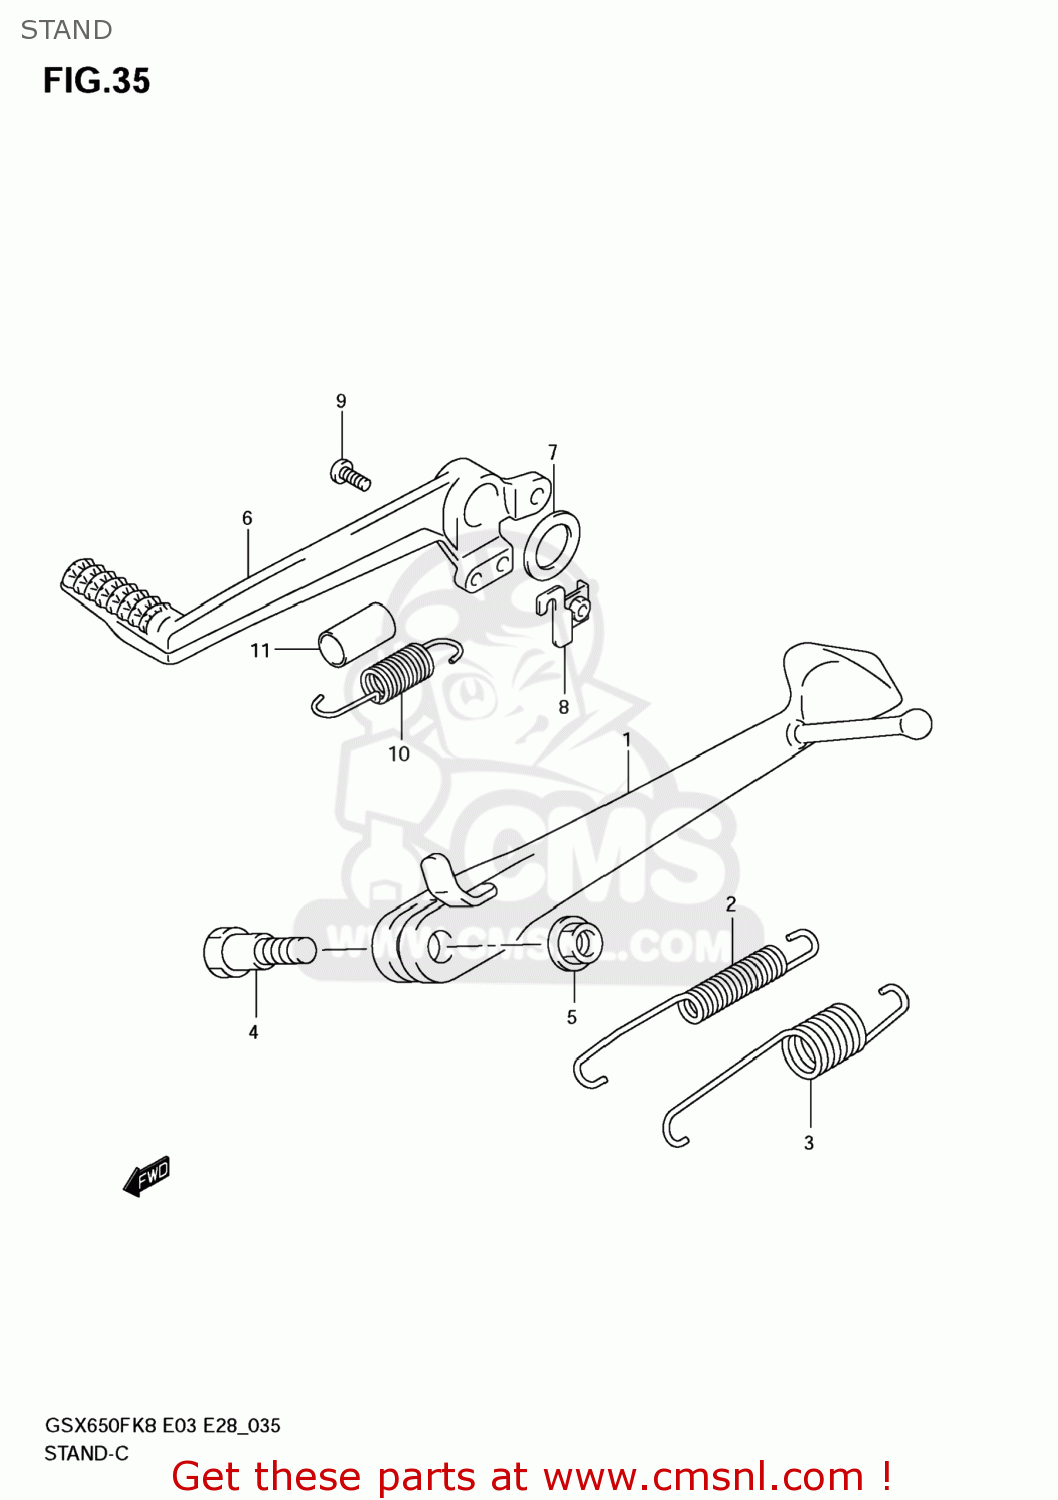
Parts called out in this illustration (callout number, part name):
1	STAND,PROP
2	SPRING
3	SPRING
4	BOLT(10X38)
5	NUT,PROP STAND
6	PEDAL,BRAKE
7	WASHER(18X24X1)
8	BRACKET,STOP LAMP SWITCH SPR
9	SCREW
10	SPRING
11	TUBE,BRAKE SPRING GUIDE
